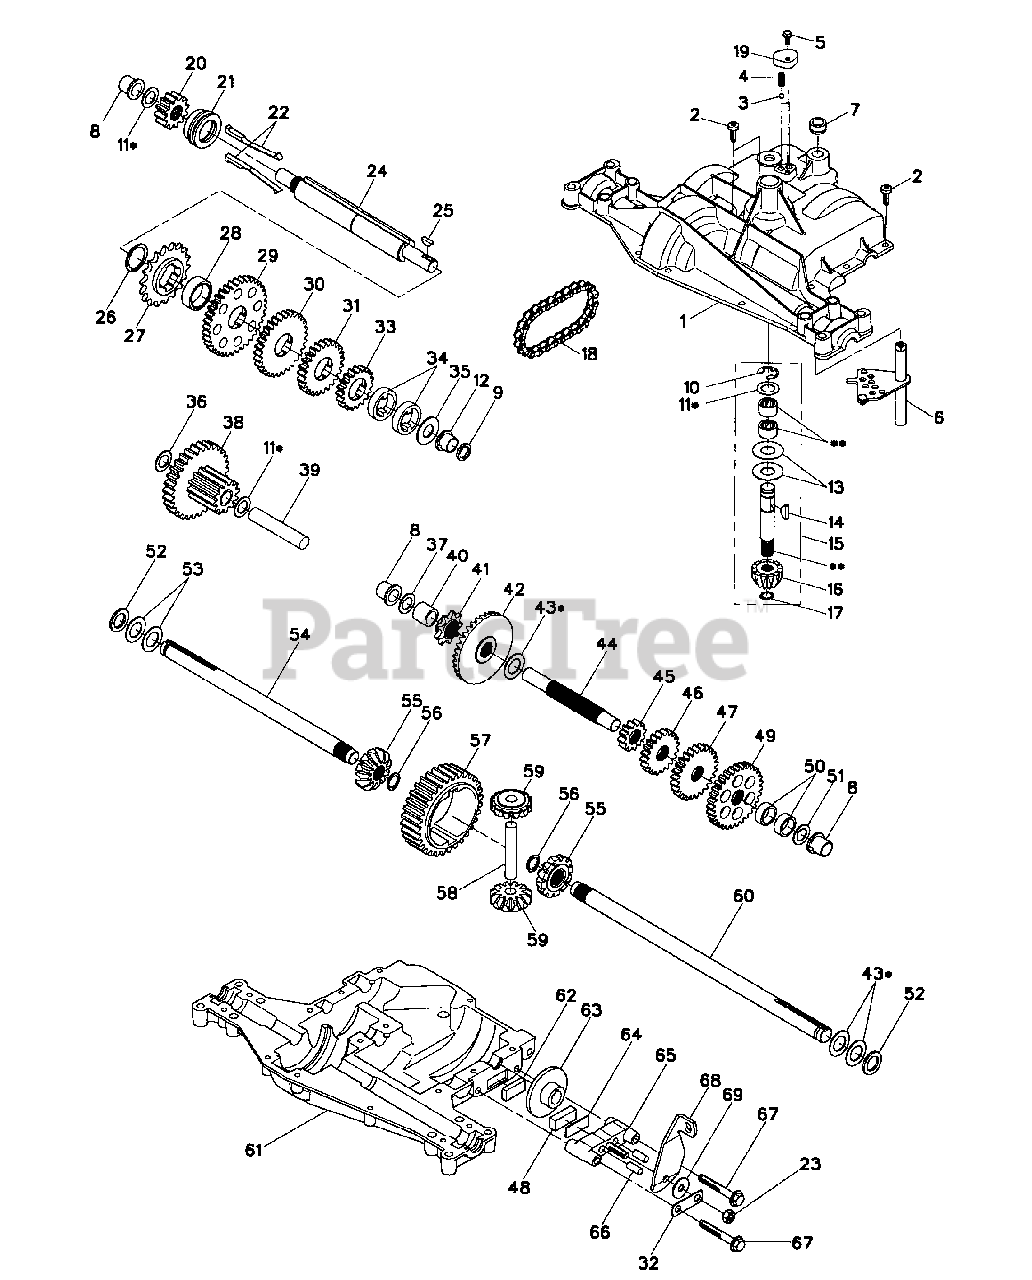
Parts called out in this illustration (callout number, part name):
1	Housing, Upper
2	Screw, Tapping, 1/4-20 X .734
3	Ball, Detent
4	Spring, Detent
5	Screw, Tapping, No. 10-24 X .482
6	Assy, Shifter
7	V-Ring
8	Bearing, Flange
9	Seal, Oil
10	Ring, Retaining
11	Assy, Kit, Shim, .625 Shaft
12	Bearing, Flange
13	Washer, Plain, .632 X 1.38 X .046
14	Key, Woodruff, No. 9
15	Assy, Kit, Input Shaft
16	Pinion, Bevel, 12T
17	Ring, Retaining
18	Chain, 24 Pitches
19	Cover, Detent
20	Gear, Spur, 12T
21	Collar, Clutch
22	Assy, Kit, Clutch Keys
23	Nut, Lock, 5/16-24
24	Shaft, Intermediate
25	Key, Woodruff, No. 61
26	Ring, Retaining
27	Sprocket, 18T
28	Spacer, 1.131 X 1.45 X .494
29	Gear, Spur, 37T
30	Gear, Spur, 30T
31	Gear, Spur, 25T
32	Bracket, Anti-Rotation
33	Gear, Spur, 19T
34	Spacer, 1.133 X 1.50 X .375
35	Washer, Plain, .640 X 1.37 X .061
36	Washer, Plain, .632 X 1.00 X .046
37	Washer, Plain, .632 X 1.00 X .031
38	Assy, Gear, Comb., 12T & 30T
39	Shaft, Idler
40	Spacer, .633 X .87 X .755
41	Sprocket, 9T
42	Gear, Bevel, 36T
43	Assy, Kit, Shim, .750 Shaft
44	Shaft, Drive
45	Gear, Spur, 12T
46	Gear, Spur, 20T
47	Gear, Spur, 25T
48	Puck, Friction
49	Gear, Spur, 31T
50	Spacer, .781 X 1.00 X .375
51	Washer, Plain, .632 X 1.00 X .060
52	Washer, Neoprene
53	Washer, Plain, .758 X 1.25 X .031
54	Axle, LH
55	Gear, Miter, 12T, Splined
56	Ring, Retaining
57	Gear, Spur, 32T
58	Shaft, Cross
59	Gear, Miter, 12T, Idler
60	Axle, RH
61	Housing, Lower
62	Puck, Friction
63	Disc, Brake
64	Spacer, Brake Puck
65	Jaw, Brake
66	Pin, Dowel
67	Screw, Tapping, 5/16-18 X 2.35
68	Lever, Actuating
69	Washer, Plain, .321 X 1.00 X .055
